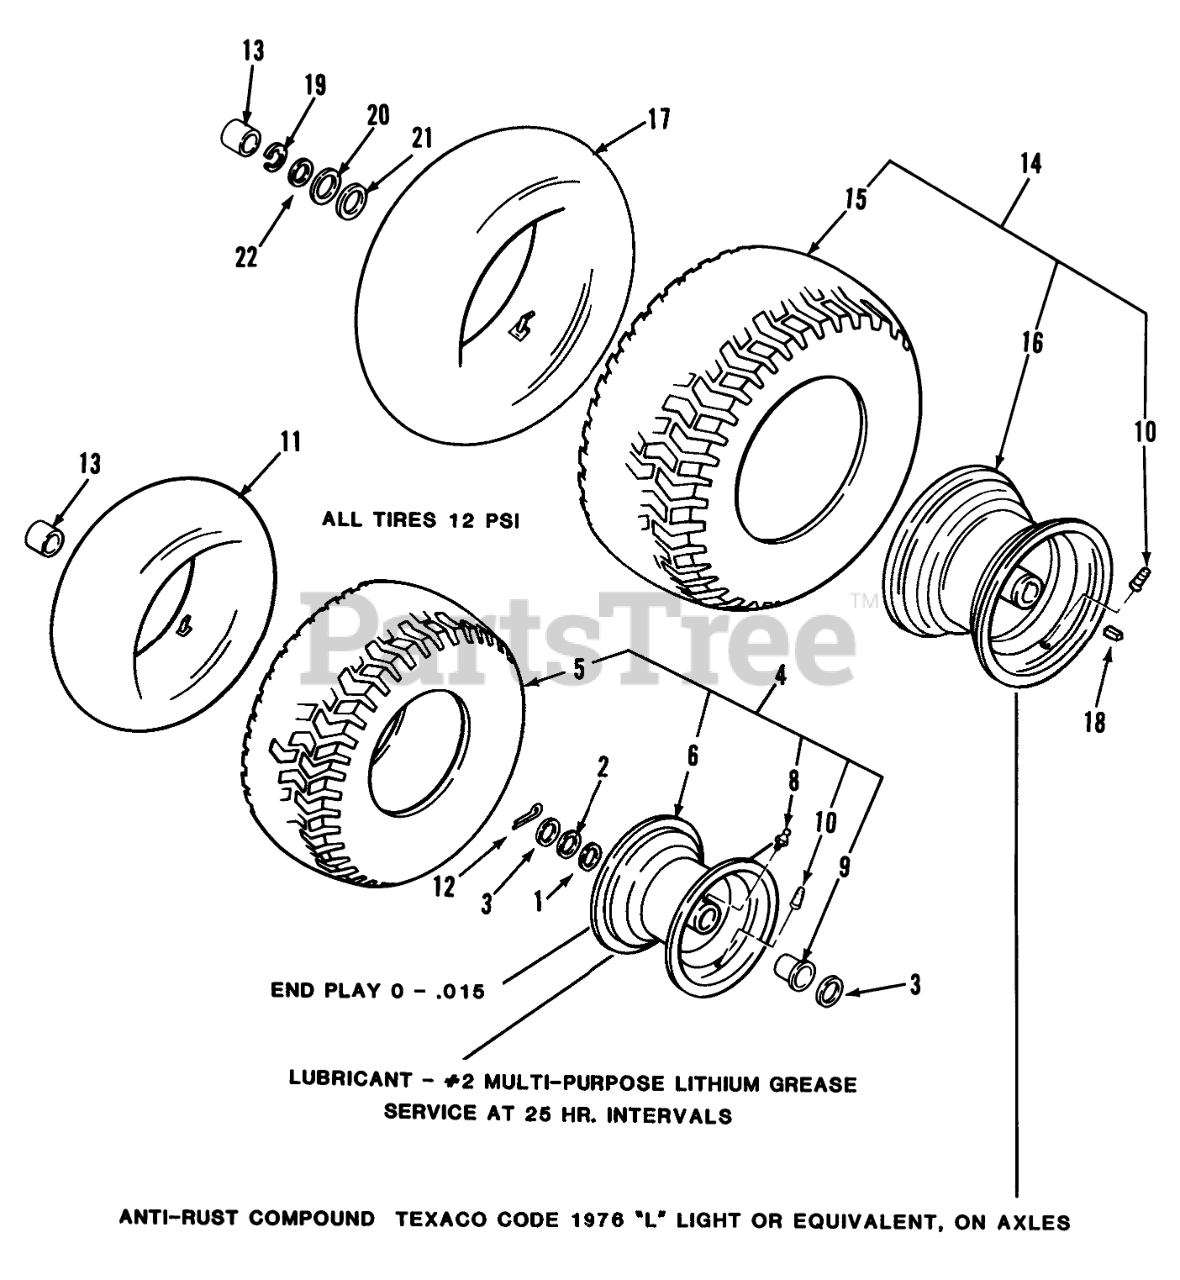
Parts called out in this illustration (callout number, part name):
1	WASHER-SHIM
2	WASHER
3	WASHER-FLAT
4	Front Wheel and Tire 15 x 6.00-6 (Includes items 5, 6, 8, 9 & 10)
5	TIRE-15 X 6.00-6
6	Front Wheel Assy (Includes Wheel with items 8, 9, & 10)
8	ZERK-GREASE
9	BUSHING
10	VALVE
12	COTTER PIN-4
13	HUB CAP
14	Rear Wheel & Tire-212-5
15	TIRE-18X9.50-8 TT RS
16	Rear Wheel 212-5
17	Tube-Inner
18	SQ KEY
19	E Ring
20	WASHER-SHIM
21	WASHER
22	WASHER-FLAT
